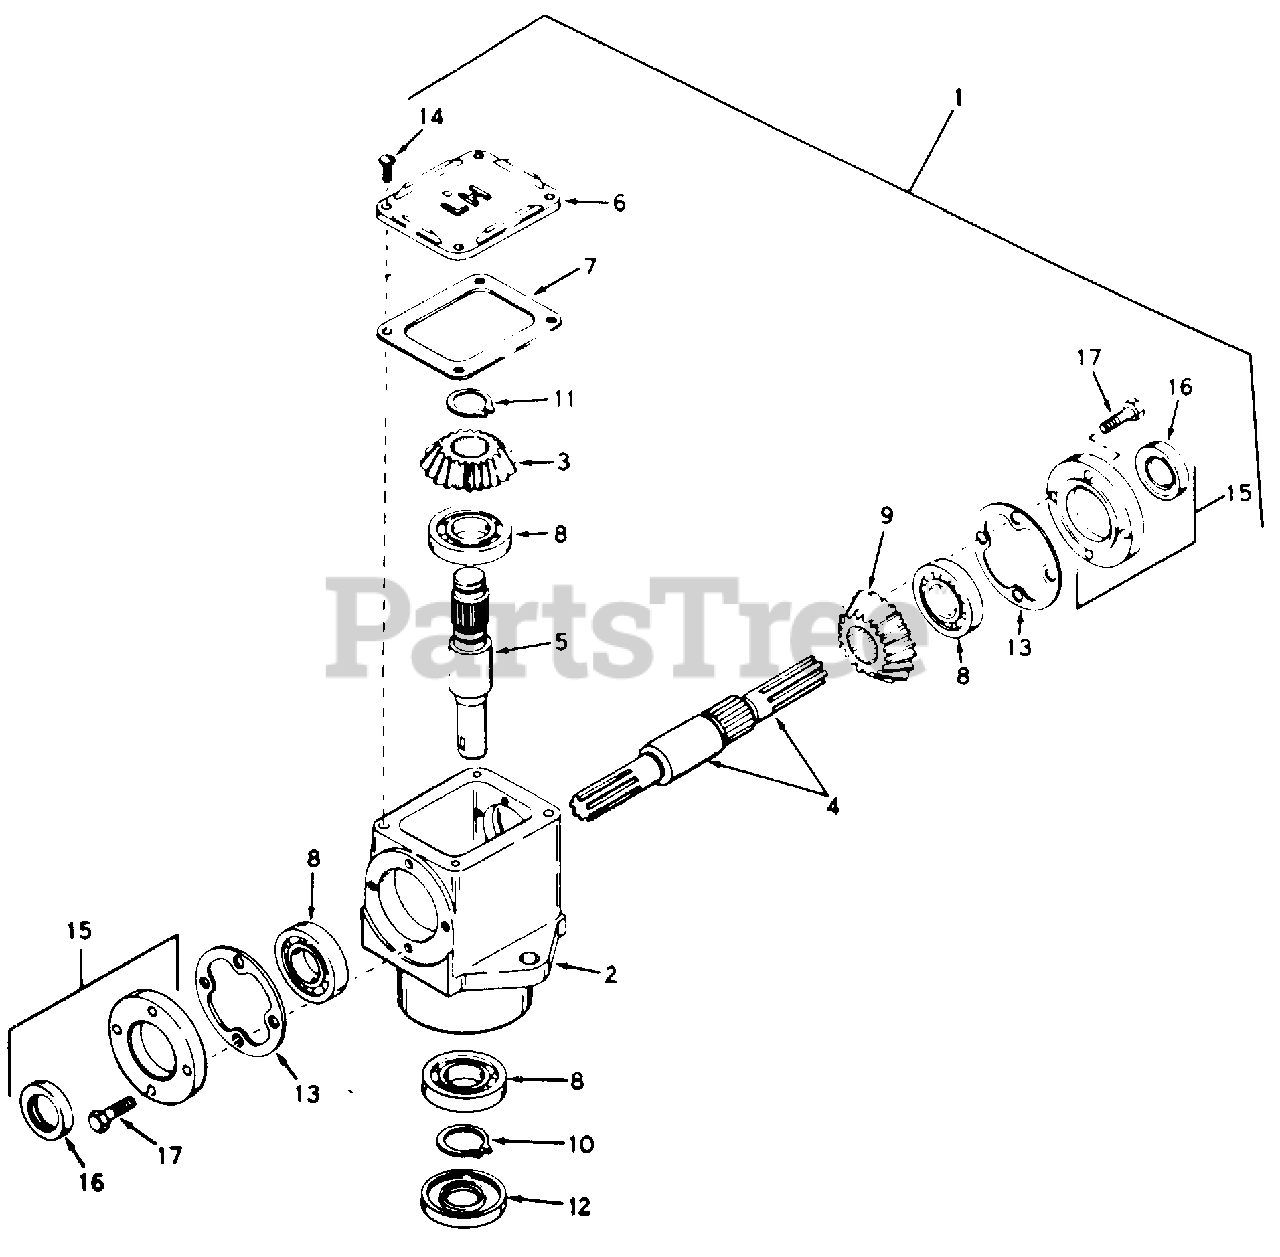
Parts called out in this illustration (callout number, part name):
1	Head Ass'y., T Drive
2	Housing T Drive
3	Gear, Miter
4	Shaft, Input
5	Shaft, Output
7	Gasket, Cover
8	Bearing, Ball
9	Gear, Miter
10	Ring, Snap
11	Ring, Snap
12	Seal, Oi I
13	Gasket, Cap
14	Scr., Rd. Hd. Self-Tap 10-24 x 1/2
15	Cap and Seal Ass'y.
16	Seal, Oil
17	Scr., Hex Hd. 1/4-20 x 7/8
